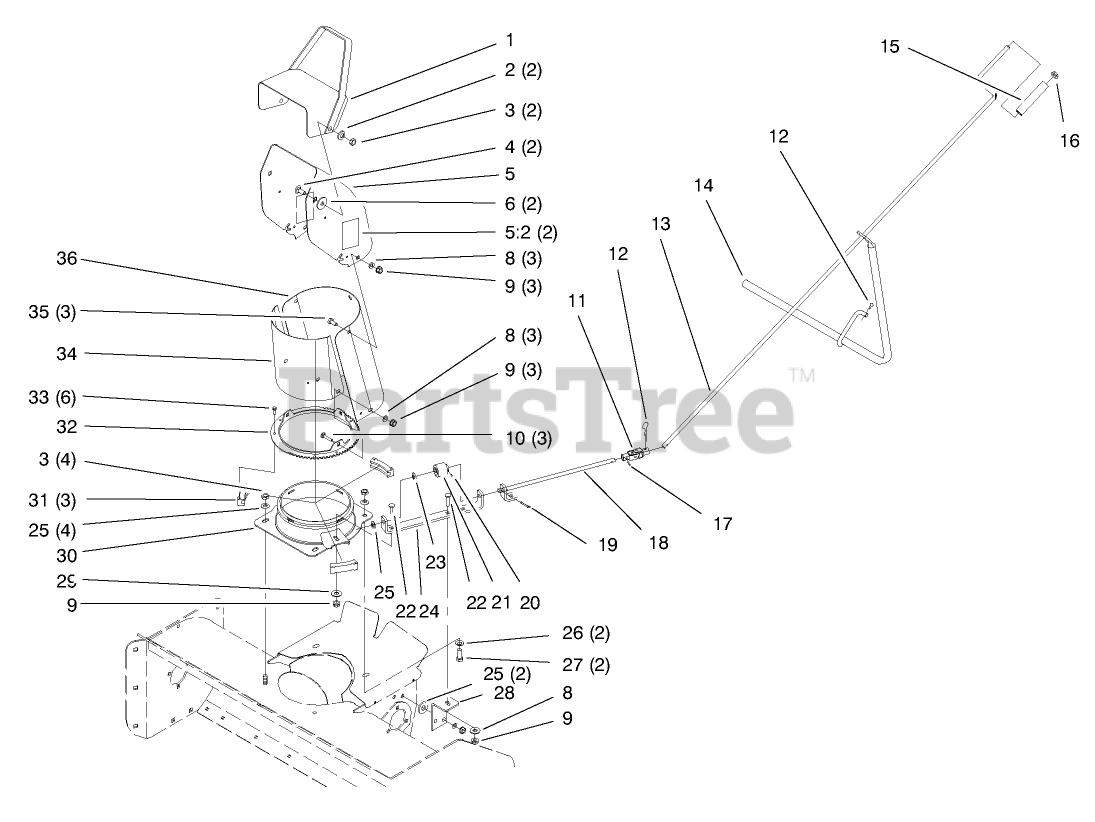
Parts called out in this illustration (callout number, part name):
1	Deflector
2	WASHER-BELLEVILLE
3	NUT-LOCK, NI
4	BOLT-CARR
5	CHUTE
5:2	DECAL-DISCHARGE DANGER
6	WASHER-RUBBER
8	WASHER-PLAIN
9	NUT-LOCK, NI
10	BOLT-CARR
11	JOINT-UNIVERSAL
12	PIN-HAIR
14	Wa-Support
15	GRIP-CONTROL, CHUTE
16	NUT - PUSH
17	PIN-SPRING
19	PIN-COTTER
20	PIN-SPRING
21	GEAR-WORM, CHUTE
22	BOLT-CARR
23	WASHER-SPRING
24	Bracket-Gear
25	WASHER-FLAT
26	WASHER-SPACER
27	SCREW-HH
28	Crank Support
29	WASHER-LOCK
30	Adapter-Wa
31	RETAINER-CHUTE
32	Screw
33	SCREW-SPECIAL
34	Shield-Deflector
35	SCREW-HH
36	EXTENDER-CHUTE, UPPER
